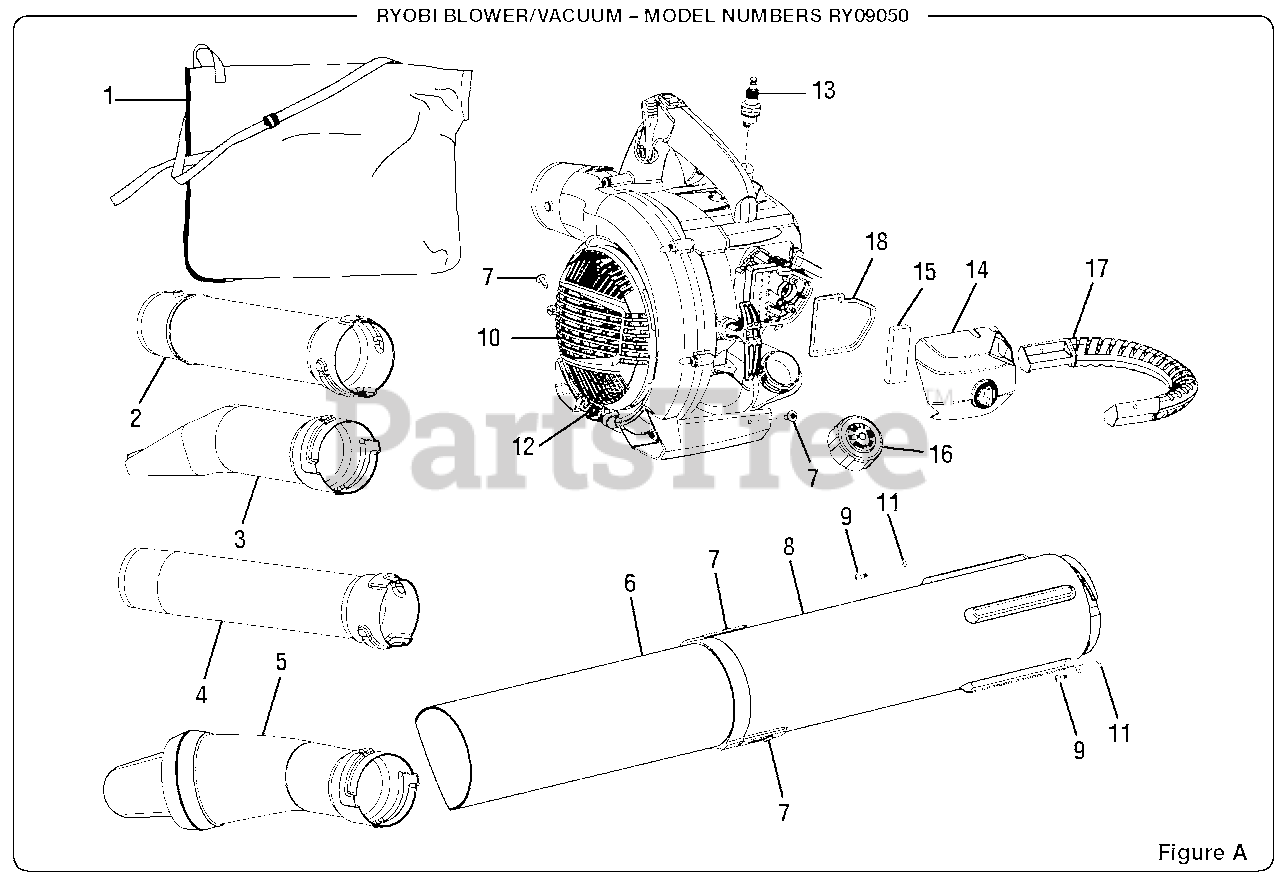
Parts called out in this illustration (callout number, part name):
1	Vacuum Bag w/Shoulder Strap
2	Upper Blower Tube
3	High Velocity Nozzle w/Leaf Scraper
4	Sweeper Nozzle
5	Vacuum Bag Adaptor
6	Lower Vacuum Tube
7	Vacuum Tube Screw (10-14 x 1/2 In.)
8	Upper Vacuum Tube
9	Screw (1/4-20 x 3/4 In.)
10	Vacuum Door
12	Vacuum Door Spring
13	Spark Plug (RCJ6Y)
14	Air Filter Cover
16	Fuel Cap Assembly
17	Vacuum Handle
18	Air Box Gasket
